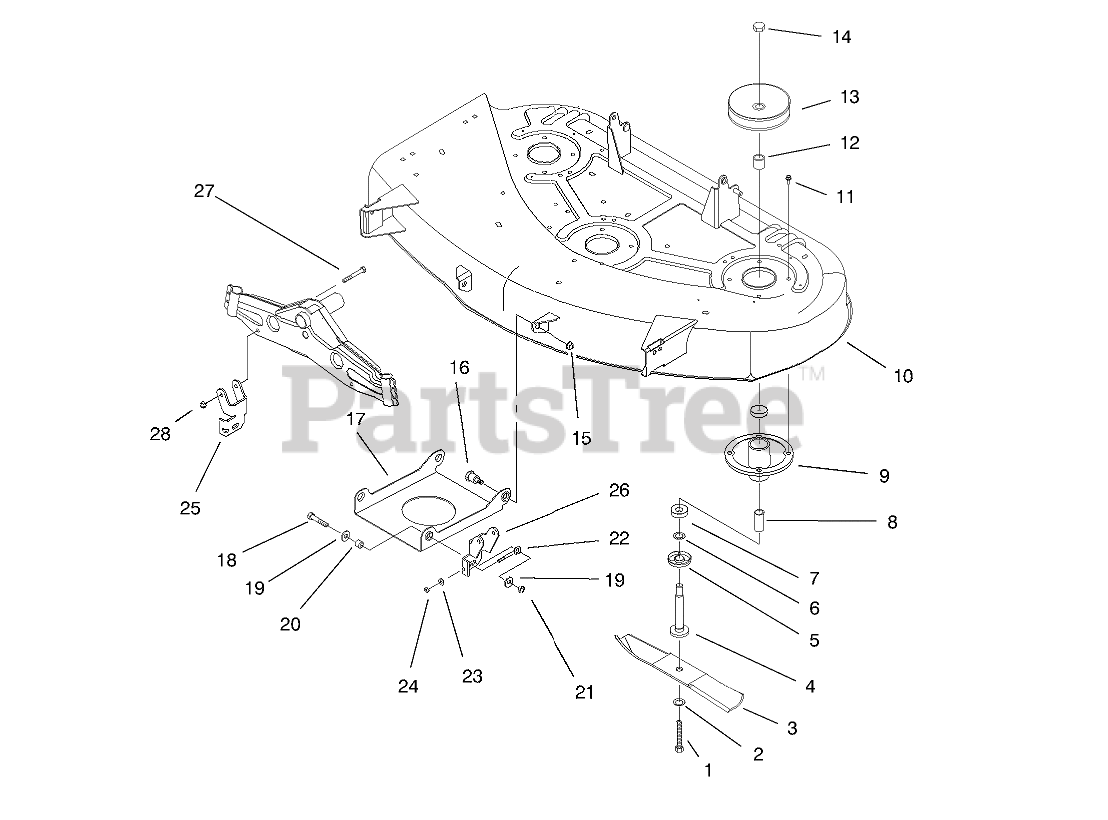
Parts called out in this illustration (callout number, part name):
1	SCREW-HH
2	WASHER-BELLEVILLE
3	Blade-Recycler
4	SHAFT-SPINDLE
5	SHIELD-BEARING
6	SPACER
7	BEARING-BALL
8	SPACER
9	HOUSING-SPINDLE
10	Deck Wa-44"
11	SCREW-TAPTITE
12	SPACER
13	PULLEY
14	NUT-HEX
15	NUT-LOCK, NI
16	BOLT-SHOULDER, HH
17	PAN-DECK SUSPENSION, FRONT
18	SCREW-HH
19	WASHER-HARDENED
20	SPACER
21	NUT-LOCK, NI
22	SCREW-ADJUSTING
23	WASHER-FLAT
24	NUT-LOCK, NI
25	BRACKET-RH
26	BRACKET-LH
27	SCREW-HH
28	NUT-LOCK, NI
